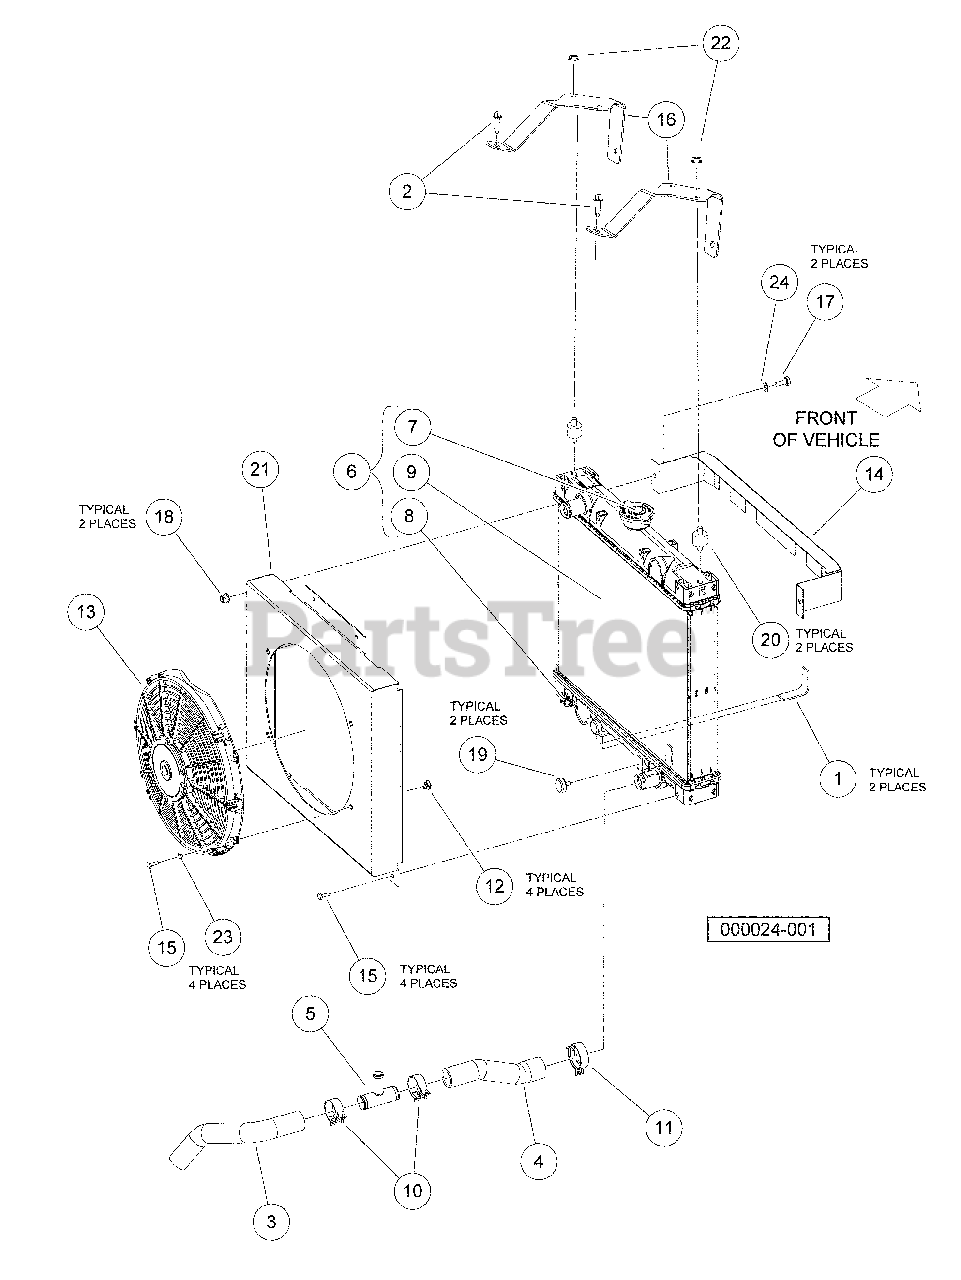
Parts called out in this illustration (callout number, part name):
1	Tape, Vinyl Foam 1/8" x 3/4"
2	Screw, M8X1.25X30, Hex
3	Hose, Coolant Lower Pipe
4	Hose, Coolant Lower Rad
5	Tee, Coolant Fill
6	Exchanger, Engine Coolant
7	Cap, Radiator
8	Drain Cock, Radiator
9	Radiator
10	Clamp, Hose, Ctb 35mm
11	Clamp, Hose, Ctb 38mm
12	Nut, Self Retaining
13	Fan, Cooling 12 In Elect
14	Guard, Radiator, Top
15	Bolt, M6 X 1 X 16 Loctite
16	Bracket, Upper Radiator Mount
17	Bolt, M8 X 1.25 X 20
18	Lock Nut, Flg M8 X 1.25 Nylon
19	Bumper, 13mm Stud
20	Isolator, Twin-Stud
21	Shroud, Radiator Fan
22	Nut Flg, M8 X 1.25 Serrated
23	Washer, M6
24	Washer, M8 Hard
